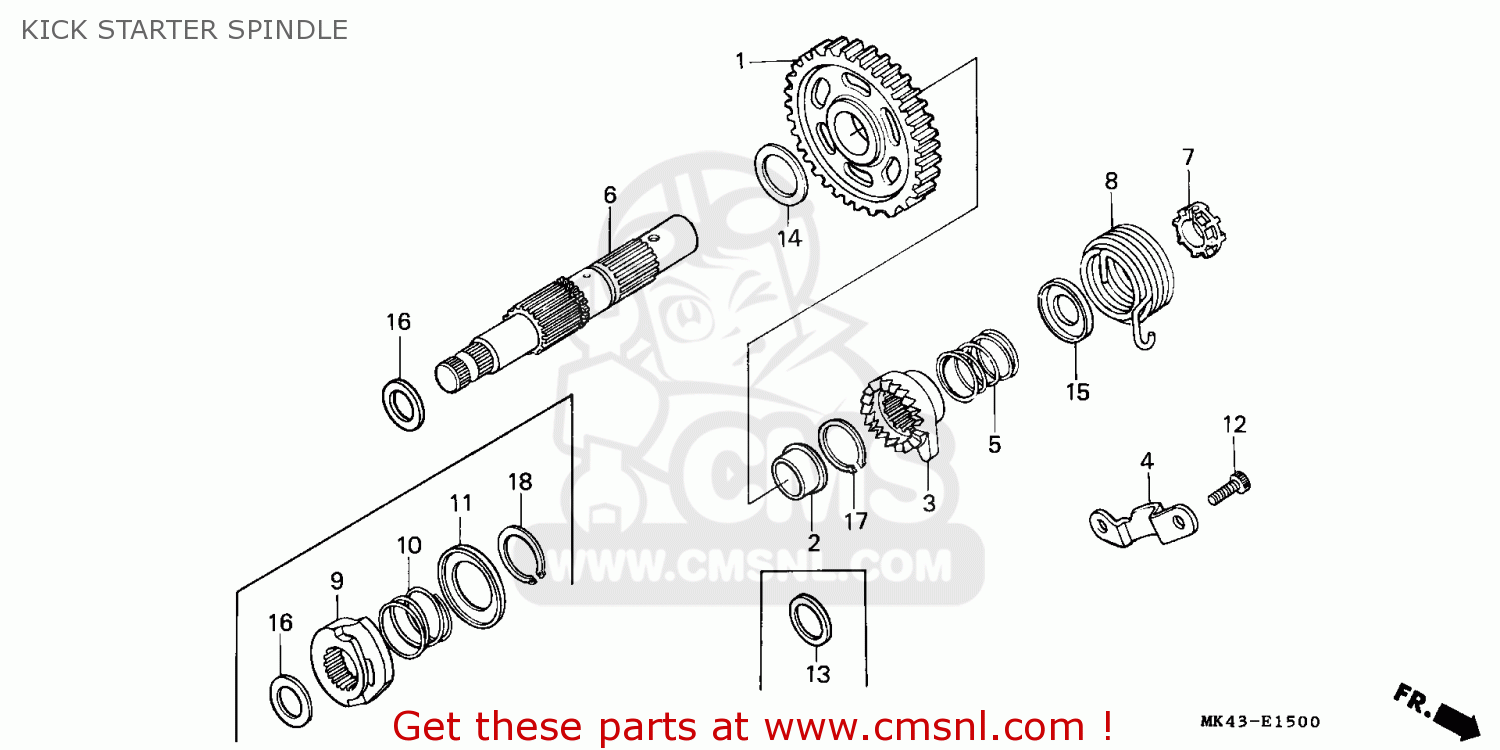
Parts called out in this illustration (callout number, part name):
1	PINION,ONLY KICK
2	COLLAR,KICK START
3	RATCHET,KICK STAR
4	PLATE,KICK STOP
5	SPG,KICK START.
6	SPINDLE,KICK STAR
7	COLLAR,KICK START
8	SPRING,KICK START
9	CAM,KICK,SHAFT
10	SPRING,CAM RESET
11	SEAT,CAM RESETSPG
12	BOLT,SOCKET,8X20
14	WASHER,22X46X3
15	WASHER,KICK SPRIN
16	WASHER,THRUST
17	CIR-CLIP,22MM
18	CIRCLIP,24MM
